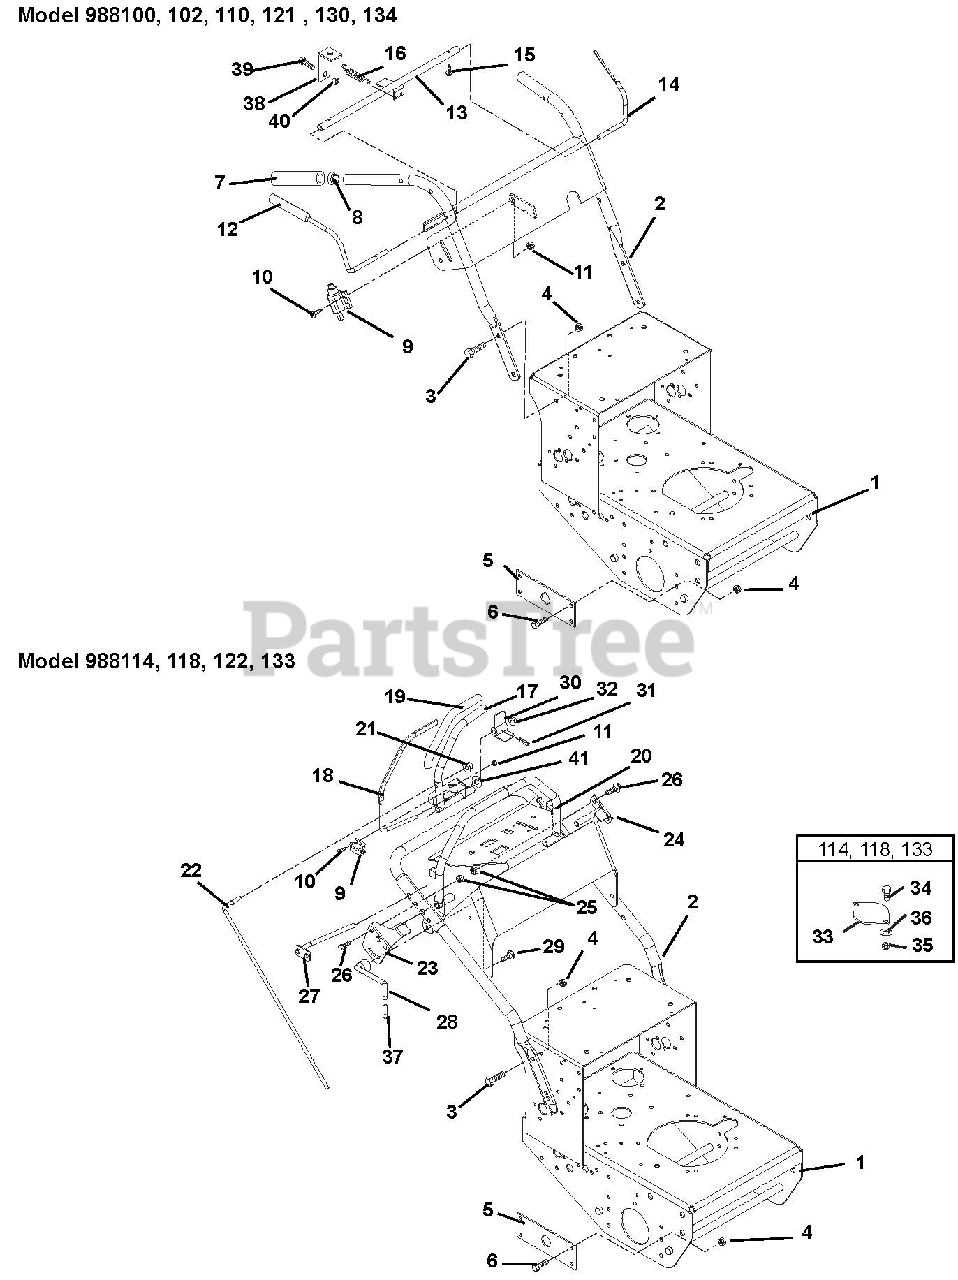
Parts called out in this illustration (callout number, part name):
1	Kit, Frame with Decals
1	Kit-Frame with Decals - 1334
2	Kit, Handlebar with Decals GR13
2	Kit, Handlebar with Decals GR15
2	Kit, Handlebar with Decals GR13/15-Pro Steer
2	Kit, Handlebar with Decals - 1334
3	Bolt, Hex .38-16 x 1.00 Grade 5
4	Nut, Locking-Nylon .38-16
5	Plate, Support
6	Bolt, Hex .38-16 x 1.00 Grade 5
7	Grip, Handlebar
8	Caplug, Handlebar
9	Switch, Interlock
10	Screw, Machine 10-24 x .75 Hex Washer Head
11	Nut, Locking-Nylon 10-24 with Insert
12	Lever, Right Hand-Operator Presence
13	Weldment, Pivot Tube
14	Lever, Left Hand-Operator Presence
15	Screw, Tapping 8-32 x .50 Hex Washer Head
16	Spring, Tension .047 x .438 x 1.45
17	Weldment, Lever-Right Hand Speed Control
17	Weldment, Lever-Left Hand Speed Control
18	Lever, Operator Presence
19	Grip, Handlebar
20	Weldment, Speed Control Stop
21	Ring, Retaining-External .375 x .010
22	Rod, Steering
23	Weldment, Control Stop Limiter-Right Hand
24	Weldment, Control Stop Limiter-Left Hand
25	Nut, Locking-Top-Flange .31-18
26	Bolt, Hex .31-18 x 1.75 Grade 5
27	Weldment, Speed Control Pivot- Right Hand
27	Weldment, Speed Control Pivot- Left Hand
28	Lever, Control Stop Lock
29	Bolt, Round Head Square Neck .38-16 x .75 Grade 2
30	Actuator, Switch
31	Pin, Roll .125 x .75
32	Nut, Push .312
33	Plate, Cover
34	Bolt, Hex .38-16 x .75 Grade 5
35	Nut, Locking-Flange .375-16
36	Washer, Flat-Steel .406 x .812 x .065
37	Grip, Hand Clutch Lever
38	Bracket, Brake Link
39	Bolt, Hex .25-20 x .75 Grade 5
40	Nut, Locking Nylon .25-20
41	Washer, Wave
